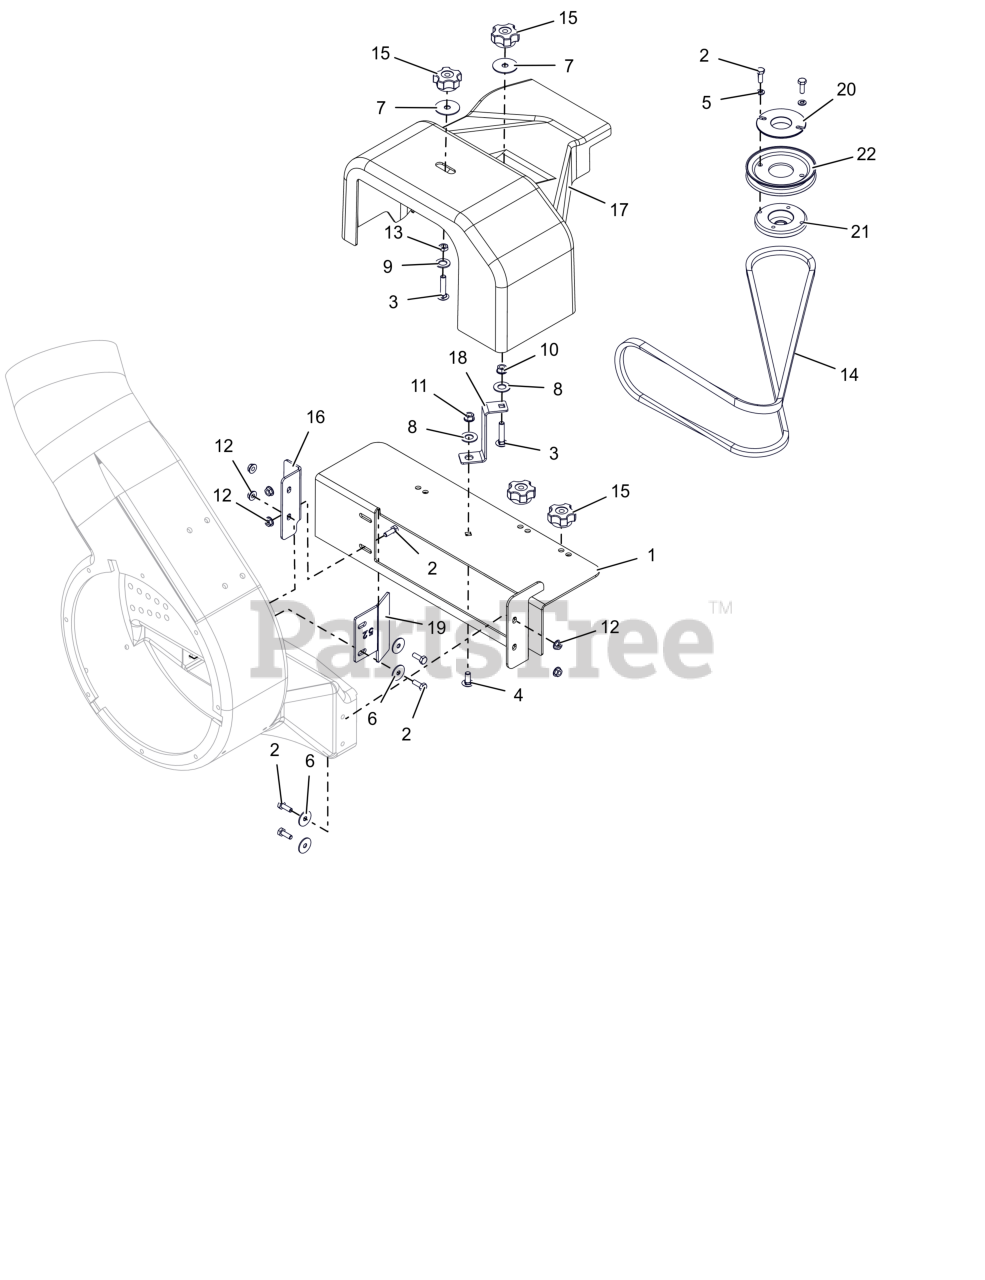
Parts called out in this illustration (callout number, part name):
1	WLDMT, BLT MOUNT BRKT (BLACK)
2	BLT, HEX .25-20X.75 G5 ZCC
3	BLT,RHSN .31-18X1.50 G5 ZCC
4	BLT, RHSSN.31-18X.750 G5 ZCC
5	WSHR,LK-REG .250X.062 ZCC
6	WSHR,FLT .281X1.000X.063 ZCC
7	WSHR,FLT .380X1.50X.062 ZCC
8	WSHR, FLT .505X1.00X.062 ZCC
9	WSHR, FLT .505X.880X.072 ZCC
10	NUT,SPNLK-FLG .31-18 G5 ZCC
11	NUT,LK-CTR-FLG .31-18 GF ZCC
12	NUT-LK-TOP-FLG .250-20 GF ZCC
13	NUT-JAM .312-18 G2 ZCC
14	V-BELT, HA-RAW EDGE
15	KNOB-CLAMPING, .312-18 NYLOC
16	BRKT, ANGLE SUPPORT (BLACK)
17	GUARD- 52" BLOWER BELT
18	BRKT, BLOWER GUARD MTG
19	BRKT, 52" BLOWER CLOSE OFF (BLACK)
20	ADAPTOR, PULLEY SHEAVE
21	ADAPTER- PULLEY IKON
22	PULLEY-V-4.25 ODX1.51 ID ZC120
